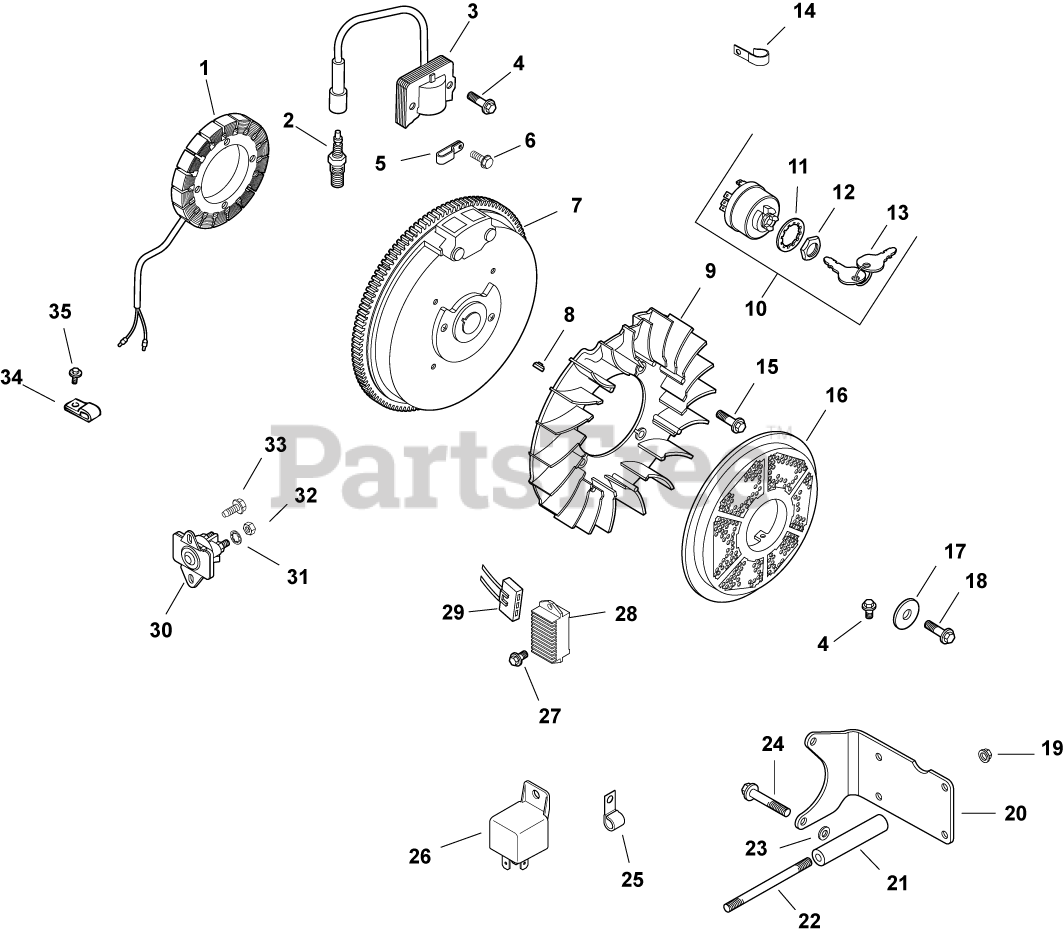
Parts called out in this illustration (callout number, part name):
1	KIT, 15 / 20 AMP STATOR
2	PLUG, SPARK (STD)
3	MODULE, IGNITION
4	SCREW, FLG THD FRM M5X.8X20-(#25086399S)
6	SCREW, FLG THD FRM M5X.8X10
7	FLYWHEEL - USE 12 025 72-S
8	KEY, 3/16" X 5/8"
9	FAN - DISCONTINUED
10	SWITCH ASSY, KEY (KM)-USE 25 099 32-S
11	WASHER, INTERNAL TOOTH
12	NUT, KEY SWITCH
13	KEY, SET -USE 48 340 01-S
14	CLIP, CABLE
15	BOLT, SHOULDER
17	WASHER, FLAT 13/32"
18	SCREW, FLG M10X1.5X45 - (#25086361S)
19	NUT, FLG M8X1.25
20	BRACKET, FUEL TANK
22	STUD, M8X1.25X133-USE 25 755 54-S
23	WASHER, FLAT 11/32"
24	SCREW, FLG M8X1.25X50
27	SCREW, FLG M6X1.0X16
28	REG/RECT-15 AMP (KM)-USE 41 403 10-S
29	CONNECTOR, BODY (KM)-USE 25 155 41-S
30	SOLENOID - WATERPROOF (KM)-USE 25 435 08
31	WASHER, INT TOOTH LOCK 1/4"
32	NUT, JAM 1/4-20 GRADE 2
33	SCREW,FLG THD FRM M6X1.0X16-(#25086397S)
34	CLIP, TUBE & WIRING (KM)
35	SCREW, M5X0.8X25 - (#25086402S)
